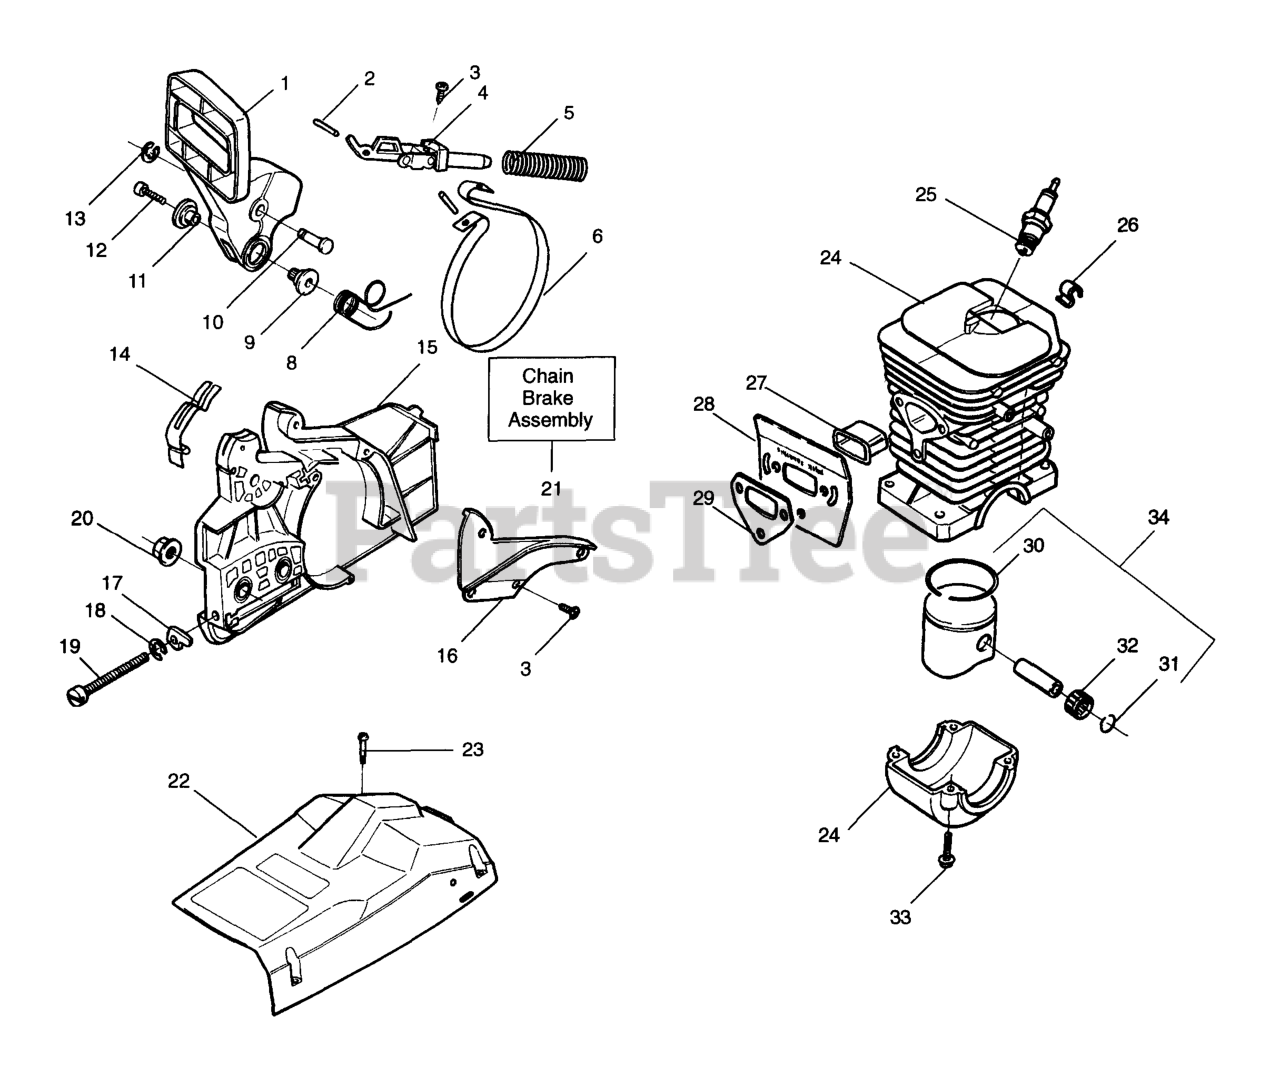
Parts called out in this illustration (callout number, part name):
1	BRAKE HANDLE ASS'Y 36/41
3	SCREW
4	Front and Rear Link Assembly
6	BRAKE BAND 36/41
8	SPRING,BRK HDL 36/41
9	PIVOT SLEEVE L
11	PIVOT SLEEVE R
14	SPRING-POSITION
15	CLUTCH COVER
16	LID, CLUTCH COVER
17	PIN-BAR ADJUST
19	BAR ADJUSTING SCREW
21	CHAINBRAKE
22	CYLINDER SHIELD ASSY
24	Cylinder Kit
25	Spark Plug (RCJ-7Y)
26	CLIP - HIGH TENSION LE
27	HEAT INSULATOR
28	MUFFLER PLATE
30	PISTON RING 36
31	C-CLIP,PSTN PIN 36/41
32	Piston Pin Bearing
33	SCREW-M5-0.8 X 25MM(TAP)
34	Piston Ring
